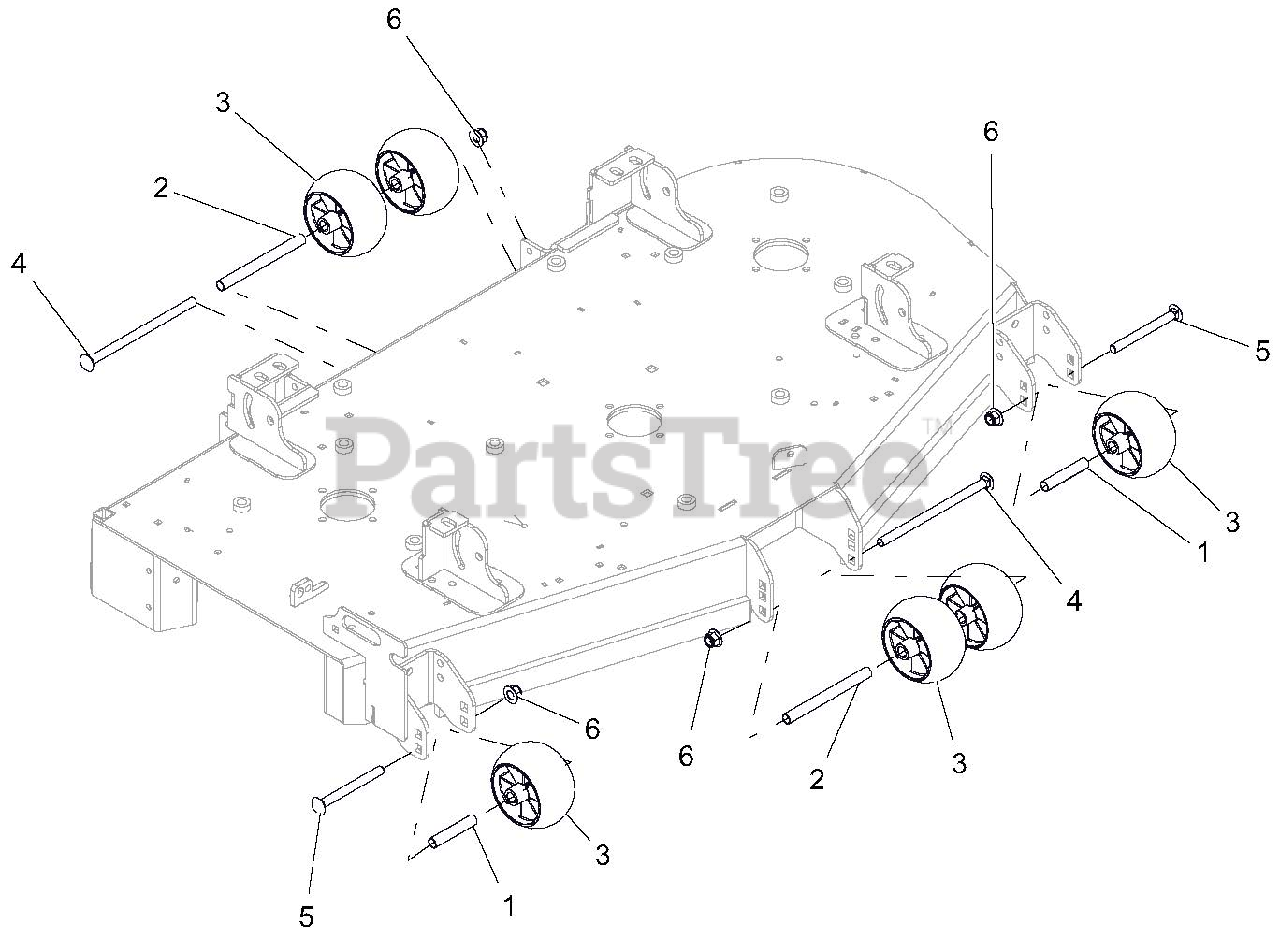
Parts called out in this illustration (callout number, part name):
1	SPACER, .510X.625X3.35
2	SPACER, .510 X .625 X 6.50
3	ANTI-SCALP WHEEL - 5X3 CTR
4	BLT-RDHDSQNK .50-13X8.50 Y
5	BLT-RDHDSQNK .50-13X5.00 G5 YWZC
6	NUT-LK-NYL-FLG .50-13 YWZC
